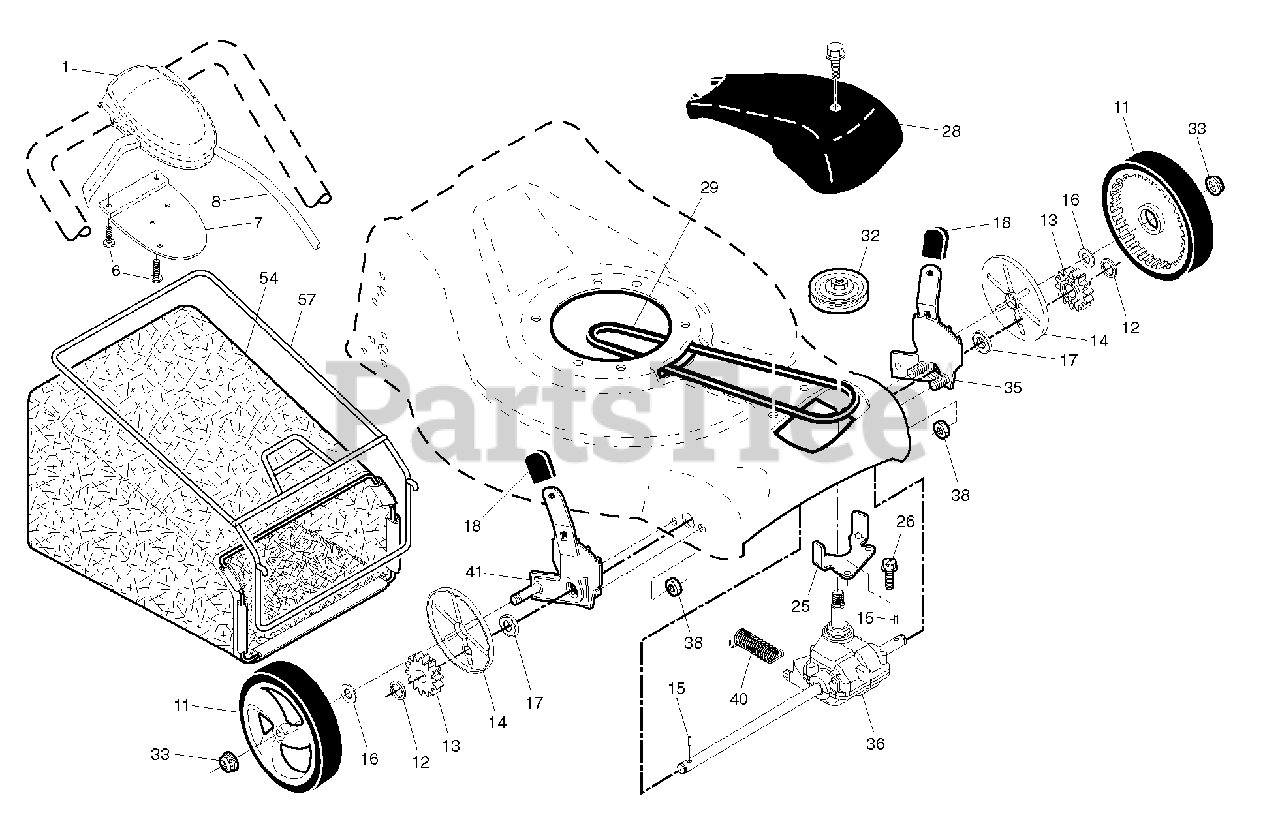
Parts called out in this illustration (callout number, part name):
6	SCREW, PHILLIPS HEAD 10 X 5/8
7	BRACKET.DRIVE.CONTROL.MOUNT
8	CABLE ASSEMBLY, DRIVE
12	E-RING 7/16 RE
13	PINION.14.TEETH.FGD
14	COVER.DUST.WHEEL
15	PAWL, DRIVE
16	WASHER FLUT
17	BEARING.ASM.
18	SELECTOR KNOB
25	BRACKET.BELT.GUIDE.22+FGD.BZP
29	BELT.DRIVE.FG
32	PULLEY.DRIVE.EZ/VARI.SCREWON
33	NUT.HEX.FLANGE.3/8-16.LOCKNUT
35	KIT ADJUSTER ASM.438151.LT
36	TRANSMISSION.21.FGD.HT.VST
38	LOCKNUT
41	KIT ADJUSTER ASM.438148 .RT
57	FRAME.GBAG.21.FWGD
